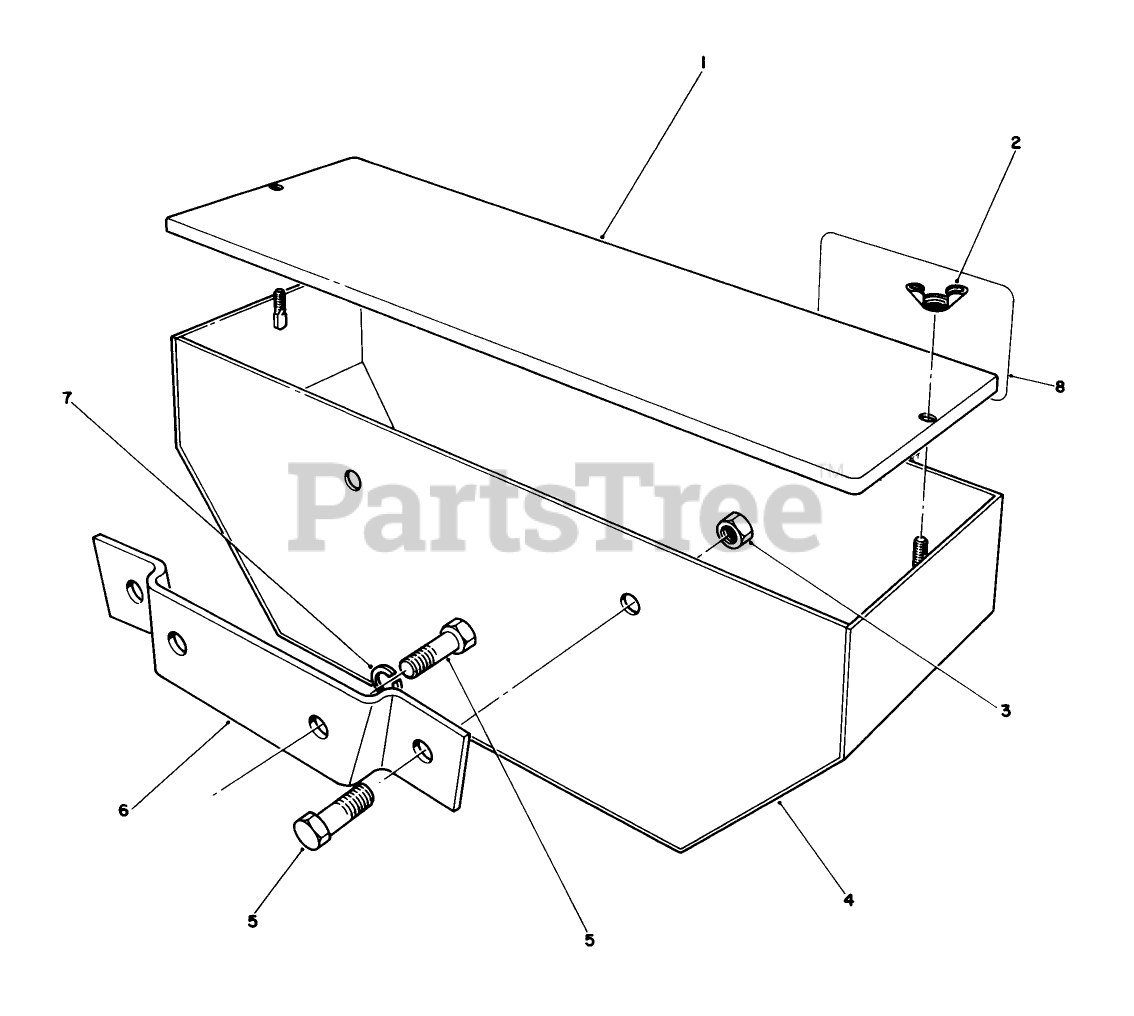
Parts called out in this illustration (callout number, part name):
1	WT BOX COVER *R
2	NUT-WING
3	NUT-LOCK, NI
5	SCREW-HH
6	MOUNT BRKT *R
7	SCREW-HH
